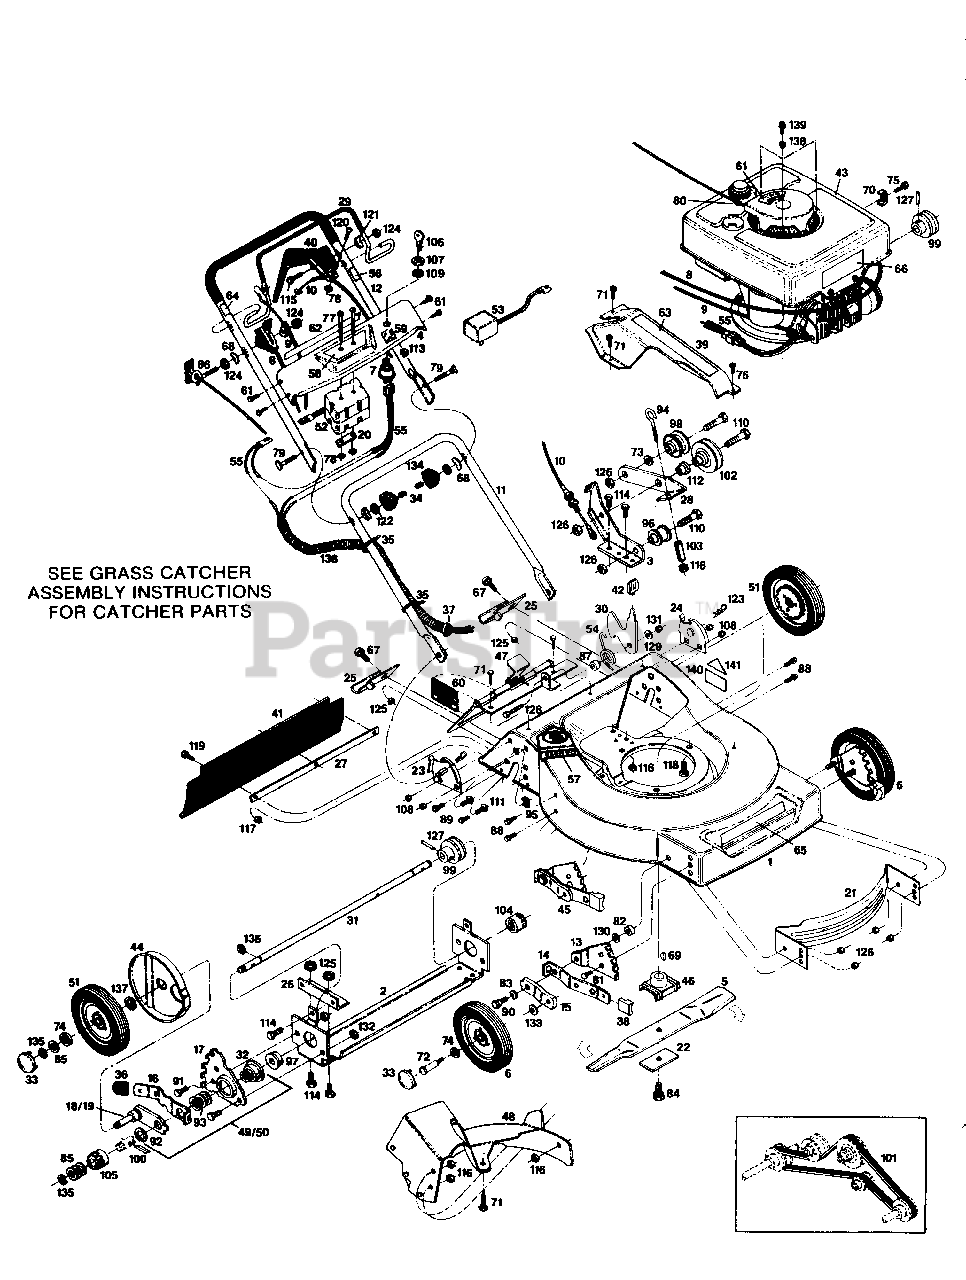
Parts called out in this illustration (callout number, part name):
2	Bracket-Drive Support
3	Bracket-ldler Mounting
4	Plate-Handle
6	Wheel-Front, 8 x 1.75
7	Switch-Start
8	Control-Throttle w/Cable
9	Cable-Engine/Blade Control
10	Cable-Wheel Drive Control
11	Handle-Lower
12	Handle-Upper
13	Plate-Back, Front Adjuster
14	Lever-Setting, Front Adjuster
15	Lever, Wheel, Front
16	Lever, Setting, Rear Adjuster
17	Plate-Back, Rear Adjuster
18	Lever-Wheel w/Pin Rear RH
19	Lever-Wheel w/Pin Rear LH
20	Plate-Reinforcing, Battery
21	Baffle-Front
22	Washer-Blade
23	Bracket-Handle RH
24	Bracket-Handle LH
25	Hook-Grass Catcher
26	Bracket-Drive Support
27	Strip-Backing
28	Arm-ldler
29	Bail-Engine/Blade Control
30	Latch-Grass Catcher
31	Shaft-Drive
32	Sleeve-Stepped, Rear Adjuster
33	Cap-Wheel Hub
34	Cap-Bolt End, Plastic
36	Tip-Adjuster Lever, Rear
37	Clip-Harness Retainer
38	Tip-Adjuster Lever, Front
39	Cover-Belt
40	Control-Wheel Drive
41	Shield-Trailing
42	Knob-Catcher Latch
43	Shroud-Engine
44	Cover-Dust, Rear Wheel
45	Adjuster-Height, Complete, Front
46	Adapter-Blade
47	Door-Catcher Opening
48	Baffle Assembly, Rear
49	Adjuster-Height, Complete, LH Rear
50	Adjuster-Height, Complete, RH Rear
51	Wheel-Rear w/Gear
52	Battery-12 Volt
53	Charger-Battery
54	Spring-Torsion, Catcher Latch
55	Harness-Wiring
56	Decal-Drive Control Instructions
57	Decal-Danger, Dischange Chute
58	Decal-Electric Start
59	Decal-Ignition Switch
60	Decal-Caution, Catcher Door
61	Decal-Warning, Blade
62	Decal-Starting Instructions
63	Decal-21" Rear Drive
64	Decal-Auxiliary Start
65	Decal-Simplicity
66	Decal-5.0 HP
67	Bolt-Carriage 1/4-20 x 5/8
68	Washer-Curved 5/16
69	Key-Woodruff #6
70	Clamp-Throttle Cable
71	Screw-Hex slotted #10 x 5/8
72	Bolt-Wheel, Front
73	Washer-Flat, 3/8 ID, 7/8 OD
74	Washer-Wheel Retaining
75	Bolt-Hex #10-32 x 3/8
76	Screw-Self Tap #6-20 x 1/2
77	Screw-Machine #8-32 x 3 1/4
78	Nut-Hex #8-32 Nylok
79	Bolt-Curved Head 5/16-18 x 2 1/4
80	Stop-Rope
81	Bolt-Carriage 3/8-16 x 3/4
82	Washer-Plastic, Front Adjuster
83	Washer-Spring, Front Adjuster
84	Bolt-Blade w/Washer 3/8-24 x 1
84	Bolt-Blade 3/8-24 x 1 1/4
85	Washer-Thrust 1/2 ID
86	Eyebolt-Rope Guide
87	Spacer-Catcher Latch
88	Bolt-Hex 1/4-20 x 1/2
89	Bolt-Self Tap 1/4-20 x 3/4
90	Bolt-Shoulder, Front Adjuster
91	Bolt-Hex, 3/8-16 x 1/2
92	Ring-Retainer 7/8
93	Washer-Spring, Rear Adjuster
94	Eyebolt-ldler Cable
95	Nut 1/4-20 Snap in
96	Pulley-ldler
97	Bearing-Drive Shaft
98	Pulley-ldler
99	Pulley-Drive
100	Pawl-Drive
101	Belt-Drive V
102	Pulley-ldler
103	Sleeve-ldler Cable
104	Pinion-Wheel Drive LH
105	Pinion-Wheel Drive RH
106	Key-Start Switch
107	Nut-Hex 5/8-32
108	Nut-Hex 5/16-18 Nylok
109	Washer-Lock 5/8
110	Bolt-Hex 3/8-16 x 1 3/4
111	Bolt-Carriage 5/16-18 x 3/4
112	Spacer-ldler
113	Clip-tinnerman
114	Bolt-Hex 1/4-20 x 5/8
115	Bolt-Hex 1/4-20 x 1 1/2
116	Nut-1/4-20
117	Nut-Hex #10-24 Nylok
118	Bolt-Hex 3/8-16 x 7/8
119	Bolt-Hex #10-24 x 1/2
120	Screw-Pan Head #8-32 x 5/8
121	Washer-Curved
122	Washer-Shakeproof 5/16
123	Cotter-Hairpin
124	Nut-Hex 1/4-20 Keps
125	Nut-Hex 1/4-20 Whiz
126	Nut-Hex 3/8-16 Lock
127	Pin-Roll 3/16 x 1
128	Bolt-Hex 1/4-20 x 1
129	Washer-Flat 1/4
130	Washer-Flat 3/8
131	Nut-Hex 1/4-20 Lock
132	Nut-Hex Jam 3/8-16
133	Washer-Belleville
134	Knob-Handle Retaining
135	Ring-Retainer
136	Wrapping-Wire Harness
137	Ring Retainer, Dust Shield
138	Retainer-Engine Shroud
139	Bolt-Hex 1 /4-20 x 1/2 TD FM
140	DECAL, Model Number
141	DECAL, OPEI
142	Lockwasher-3/8 Split HD
143	Bolt-1/4-20 x 3/8 Shaved Head
